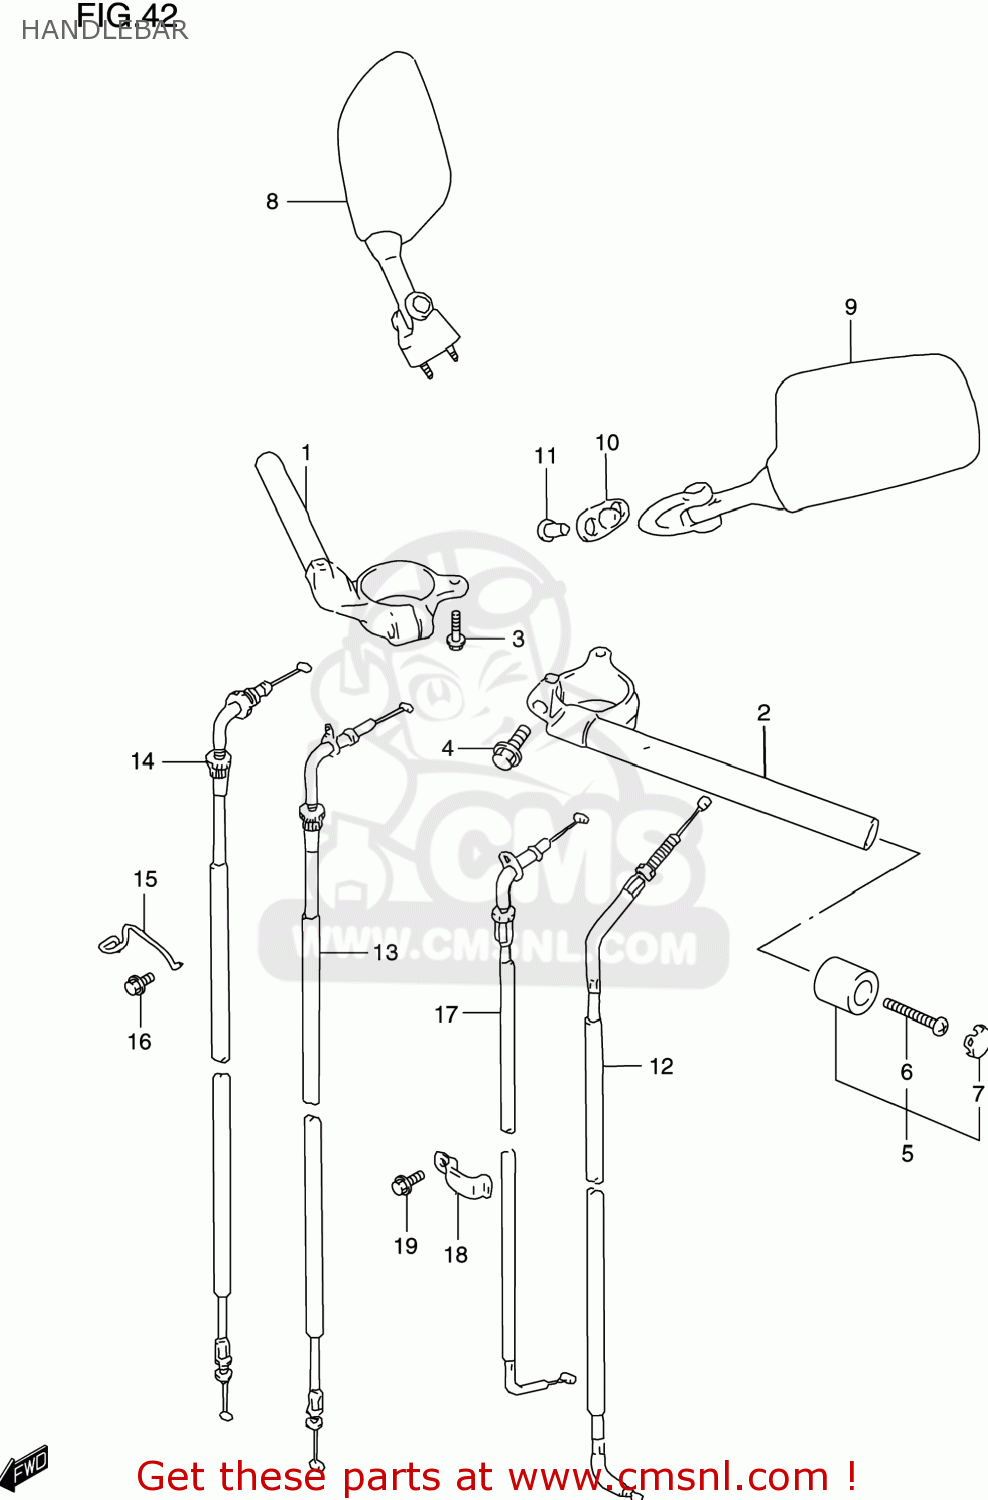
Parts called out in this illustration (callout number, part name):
1	HANDLEBAR,R
2	HANDLEBAR,L
3	BOLT
4	BOLT(8X30)
5	BALANCER SET,HANDLEBAR
6	SCREW
7	CAP,BALANCER
8	MIRROR ASSY,RR VIEW,R
9	MIRROR ASSY,RR VIEW,L
10	CUSHION,RR VIEW MIRRORR
11	NUT,RR VIEW MIRROR
12	CABLE ASSY,CLUTCH
13	CABLE ASSY,THROTTLE NO.1
14	CABLE ASSY,THROTTLE NO.2
15	GUIDE,THROTTLE CABLE
16	BOLT
17	CABLE,STARTER
18	CLAMP
19	BOLT
